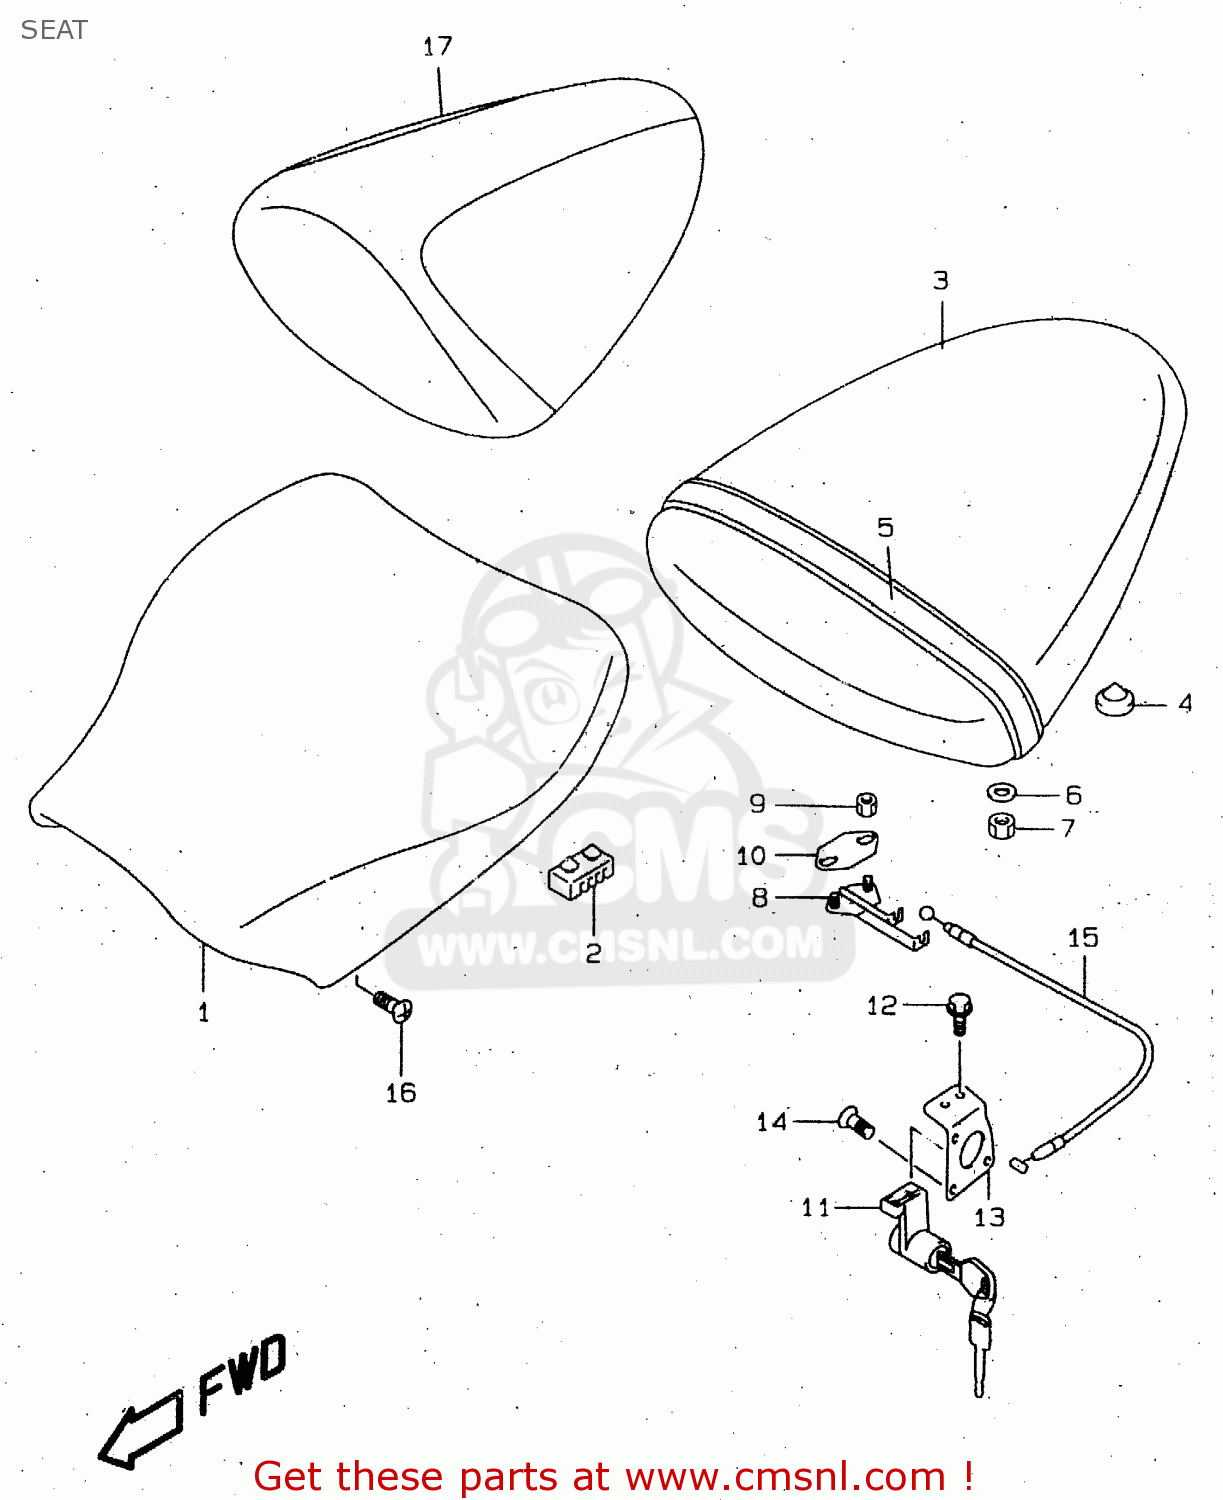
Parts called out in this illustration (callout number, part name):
1	SEAT ASSY
2	CUSHION,SEAT(40X20X15)
3	SEAT ASSY,PILLION
4	CUSHION(11.5X22X20)
5	BAND ASSY,PILLION SEAT
6	WASHER(6.5X20X1.6)
7	NUT
8	BRACKET,SEAT SUPPORT
9	NUT
10	PLATE,SEAT SUPPORT BRKT
11	LOCK SET,SEAT
12	BOLT
13	BRACKET,SEAT LOCK
14	SCREW
15	CABLE,SEAT LOCK
16	BOLT(6X18)
17	BOX,SEAT TAIL
